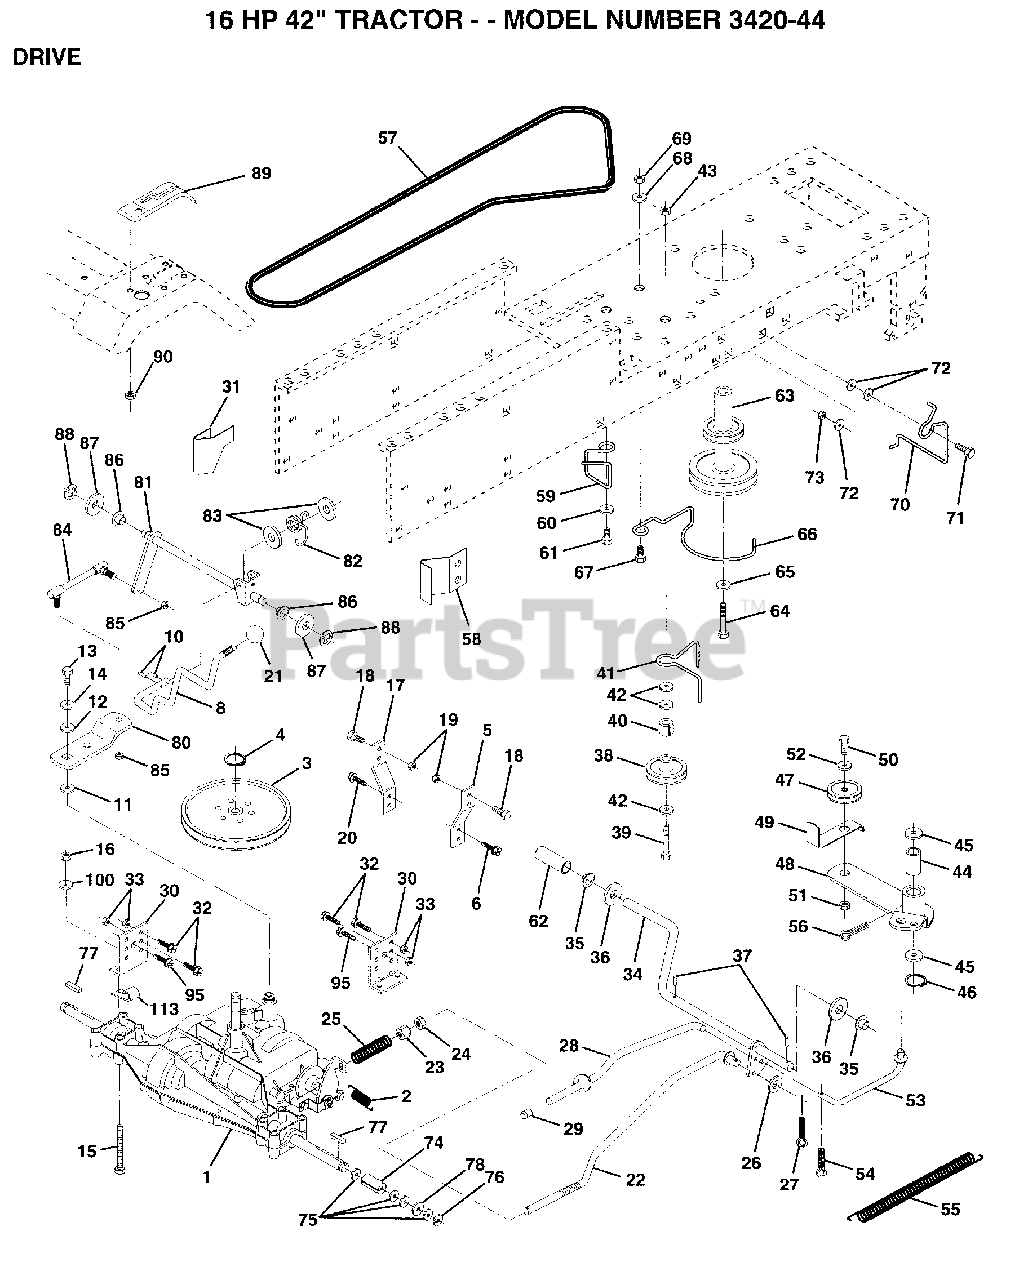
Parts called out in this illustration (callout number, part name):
3	PULLEY TRANS
5	STRAP TORQUE
6	SCREW
8	ROD SHIFT FEND LT
10	PIN COTTER 1/8
11	WASH-SHFT PLT LT
12	WASHER
14	LOCKWASHER
15	BOLT HEX
16	NUT
17	STRAP TORQUE
18	BOLT
19	NUT
20	SCREW
21	KNOB T (1/2-HOLE)
22	BRAKE ROD
23	NUT
24	NUT
25	SPRING ROD LT
26	WASHER
27	COTTER PIN
28	BRAKE PARK ROD
29	PLUNGER CAP T
30	TRANSAXLE MTG BKT
31	"KEEPER,BELT LH T"
32	BOLT
33	NUT
35	NYLON BEARING
36	WASHER LT
38	PULLEY.IDLER.FLAT
39	BOLT
40	SPACER T
41	BELT KEEPER LT
42	WASHER
43	NUT
44	"LY, BEARING"
45	WASHER LT
46	KLIP RING
48	ARM IDLER
49	RETAIN BELT
52	WASHER HYT
53	"LINK, CLUTCH T"
54	COTTER PIN
55	"SPRING, RETURN LT"
56	COTTER PIN
58	"KEEPER,BELT RH T"
59	KEEPER BELT CNTSP
60	WASHER
61	SCREW
62	PEDAL COVER T
63	PULLEY.ENGINE
64	BOLT
65	LOCKWASHER
66	KEEPER.BELT.ENG.L
67	BOLT
68	WASHER
70	KEEPER BELT ENG
71	BOLT
72	WASHER
74	SPACER LT
75	WASHER
76	E-RING LT
77	SQUARE KEY
78	WASHER
80	ARM SHIFT TRANS
81	SHAFT ASM.SHIFT
82	"SPRING,TORSION"
83	WASHER
84	TIE ROD
85	NUT 1/4-28
86	BUSHING
87	WASHER D
88	KLIP RING
90	NUT
95	SCREW
100	WASHER M
113	CLIP T
